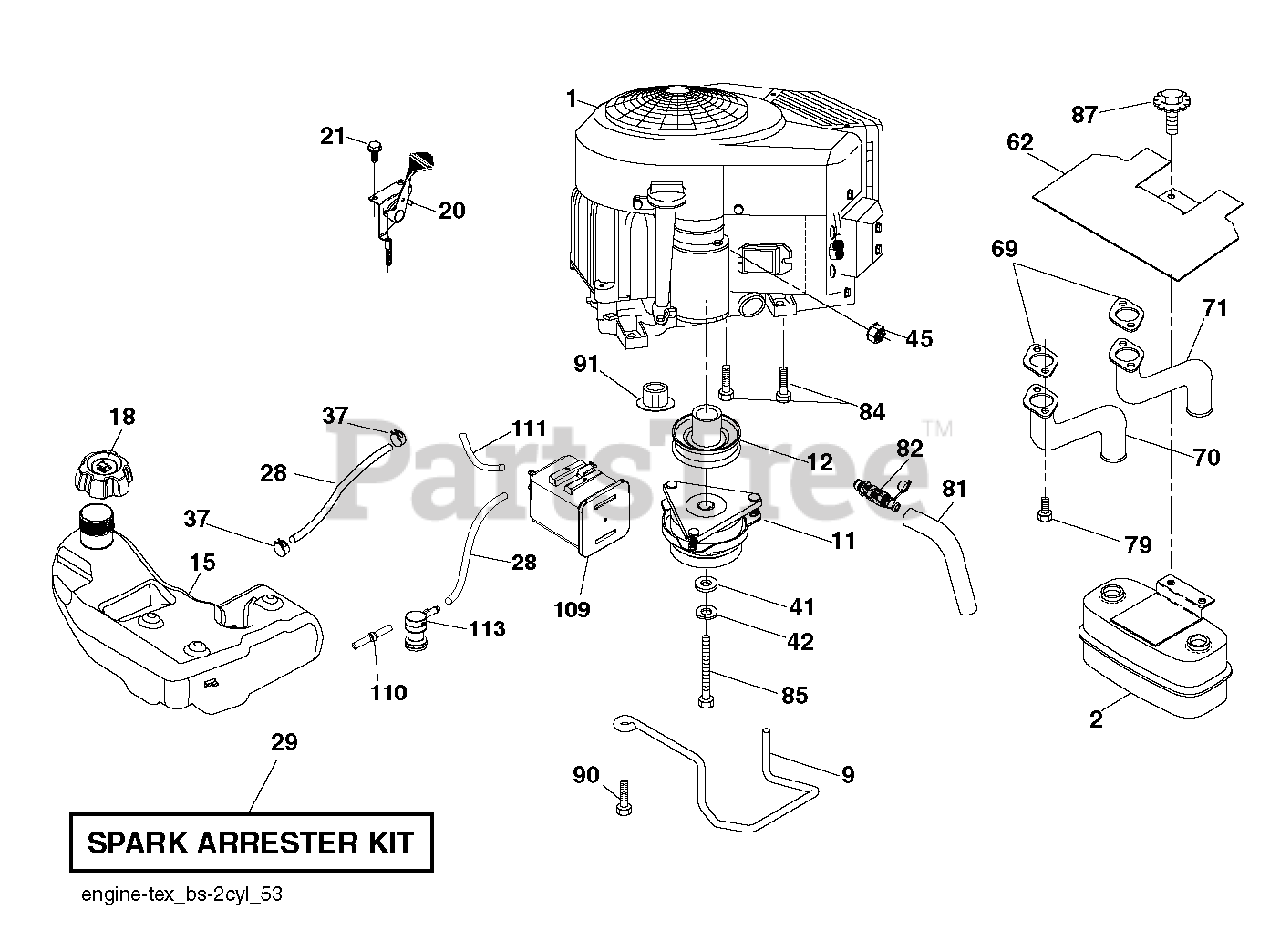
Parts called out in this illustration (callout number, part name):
2	MUFFLER.TWIN.CYL.LOW.TONE
9	KEEPER.BELT.ENGINE.4.2
11	CLUTCH.ELECTRIC.LT.48"*
12	PULLEY.ENGINE.TUFFTORQ
15	TANK.ASM.FUEL.3GA.CARB
18	RP CAP ASM
20	CONTROL.TH/CK.COBRA.B&S.TWN.
21	SCREW.#10 X 0.750.BOS
28	LINE.FUEL.64"REAR.EMIS
29	KIT.SPARK ARRESTOR 794945 B&S
37	HOSE CLAMP
42	LOCKWASHER
45	NUT
62	RP SHIELD HEAT MUFFLER
69	GASKET.MUFFLER
70	RP.EXHAUST.TUBE.LH.BS/TWIN
71	EXHAUST.TUBE.RH.BS/TWIN
79	SCREW.SOCKET.HEAD.5/16-18
81	TUBE, DRAIN OIL ASM.
82	VALUE.OIL.DRAIN
84	SCREW.3/8-16
85	BOLT HEX 7/16-20X4-1/4"
87	BOLT, 5/16-18 X 1 3/4
90	SCREW 3/8-16X1
91	BUSHING.1.375OD
109	CANNISTER, CARBON
110	VALVE.ASM.ANTI-SLOSH
111	RP PURGE LINE
113	VALVE.SLANT.CARTRDG.90 DEG.TEX
